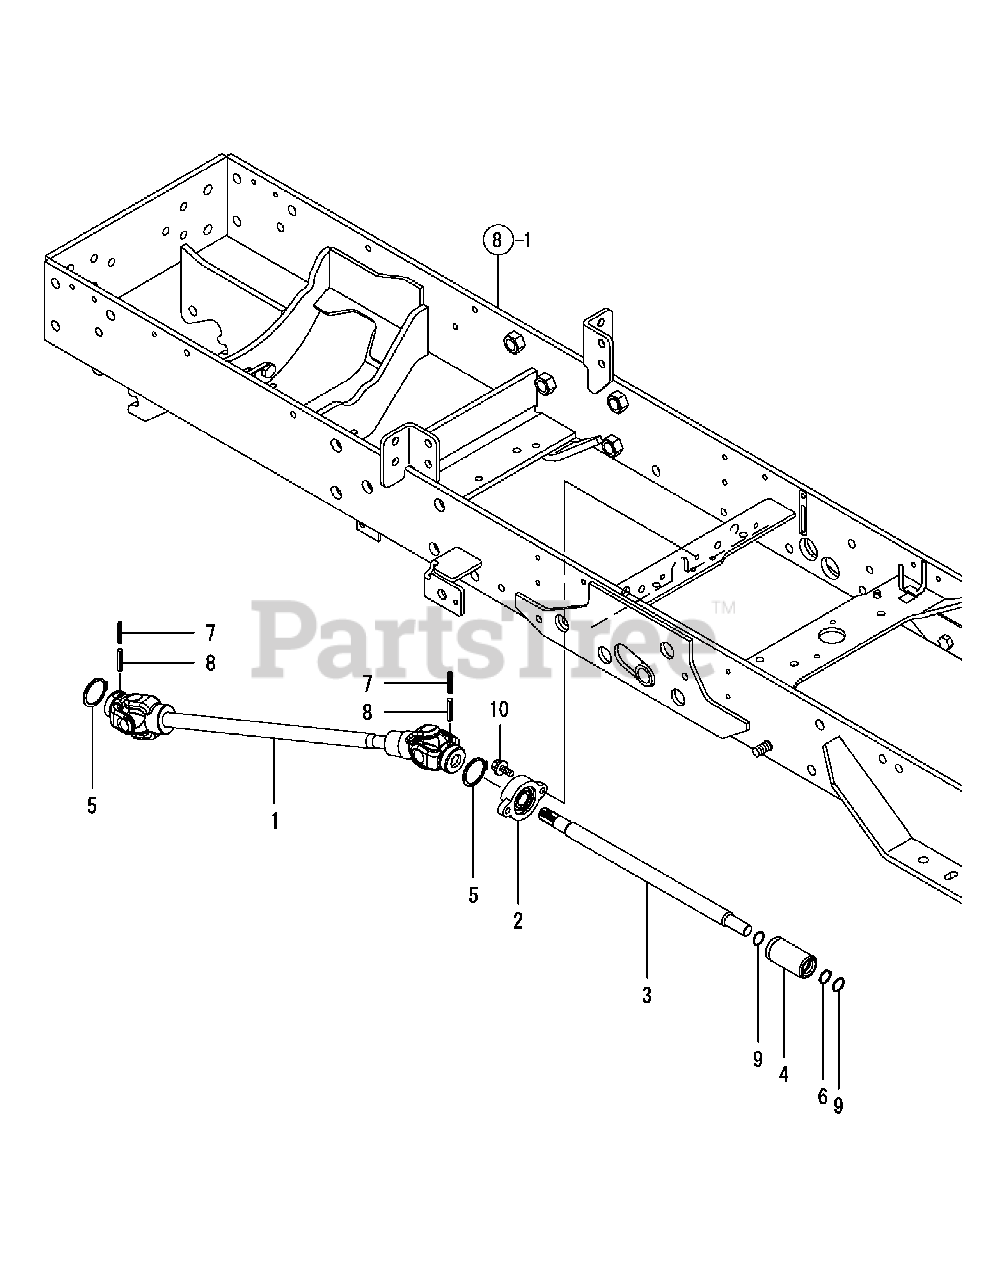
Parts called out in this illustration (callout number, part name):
1	SHAFT CMP,POP. F
3	SHAFT R, PROPELLER
4	COLLAR, SPLINE
7	SPRING PIN 3.5X32
8	SPRING PIN 6X32
9	O-RING 1A P-16.0
10	BOLT W/WASHER M8X20
